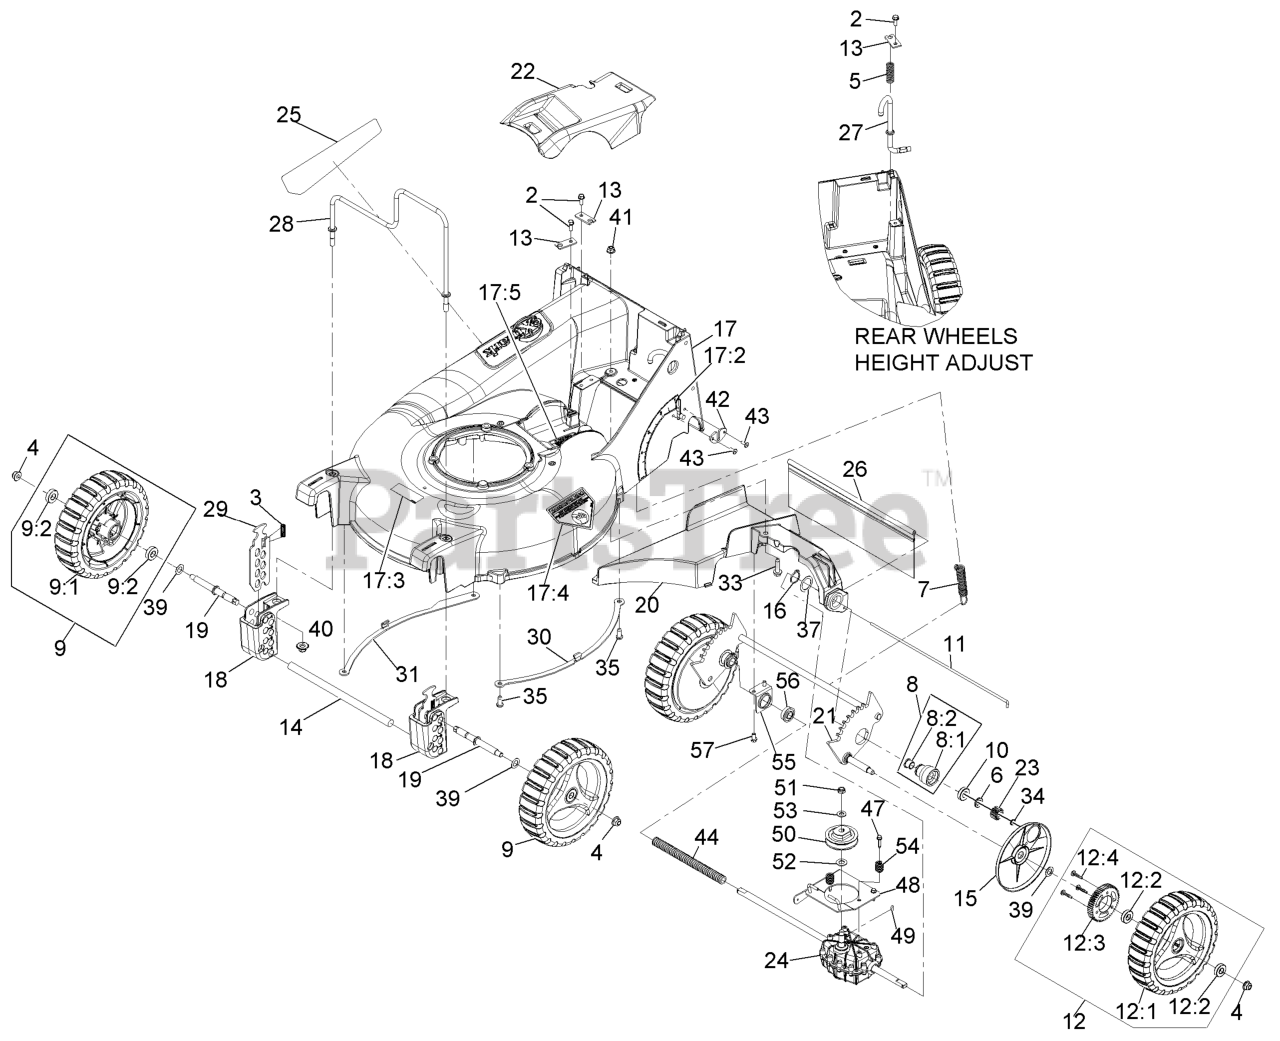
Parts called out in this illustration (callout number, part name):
2	SCREW-HWH
3	SPRING-COMPRESSION
4	NUT-HF, NI
5	SPRING-COMPRESSION
6	SPACER-BUSHING
7	SPRING-EXTENSION
8	HOUSING ASM
8:1	HOUSING-BEARING
8:2	BEARING-FLANGE
9:2	BEARING-BALL
10	BEARING-BALL
11	ROD,SHIELD
12:2	BEARING-BALL
12:4	SCREW-DRIVE
13	BRACKET,MOUNT
14	ROD,BUMPER
15	COVER,GEAR
16	RING-RETAINING
17	DECK W/DECALS
17:2	DECAL-HEIGHT OF CUT
17:3	DECAL-BLADE
17:4	DECAL-DANGER
17:5	DECAL-COVER MISSING
18	BLOCK,FRONT QUADRANT
19	AXLE-WHEEL
20	BRACKET-TRANSMISSION AND
21	WLD,REAR AXLE P21
22	COVER,BELT
24	TRANSMISSION-HD, 4.5/1
25	DECAL-COMM 21 X-SERIES
26	SHIELD-TRAILING P21
27	ROD-HEIGHT ADJ P21
28	GUARD,ENGINE
29	PLATE, FRONT HEIGHT
33	SCREW-HWHTF
34	RING-RETAINING
35	SCREW-BHTF
39	WASHER-PLAIN
40	Nut-Nyloc 3/8-16 Flg
41	NUT-HF, NI
42	PLATE,WEAR
43	RIVET-BLIND
44	COVER-SHAFT-DRIVE
47	SCREW-SPECIAL
48	TRANSMISSION PLATE ASM
49	KEY-WOODRUFF
51	NUT-HEX
52	WASHER-THRUST
53	WASHER-FLAT
54	SPRING,COMPRESSION
56	BEARING-BALL
57	SCREW-HWH
